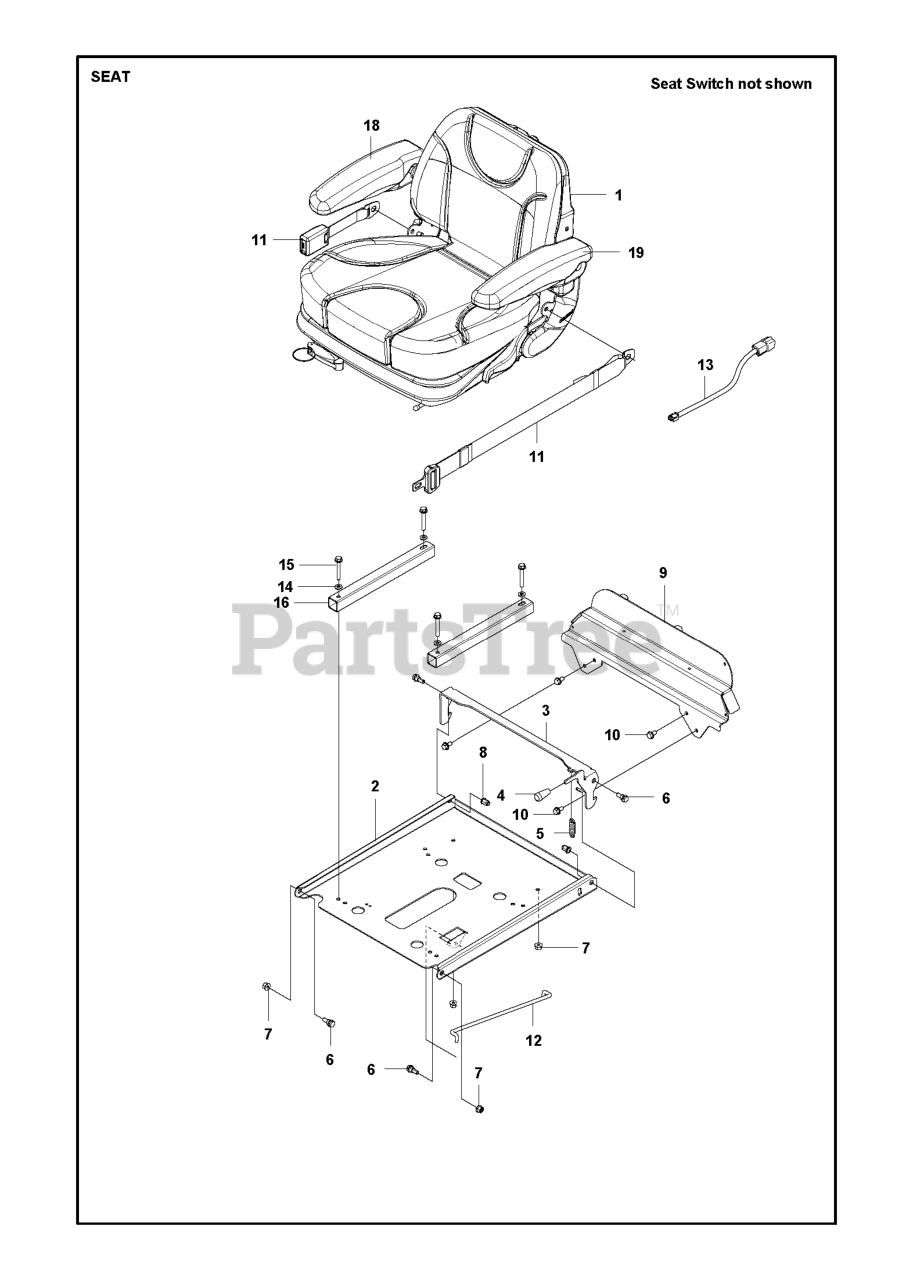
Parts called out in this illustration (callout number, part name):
5	DRAW SPRING L=50
7	NUT FLANGE
14	WASHER BRB 8.4X17
